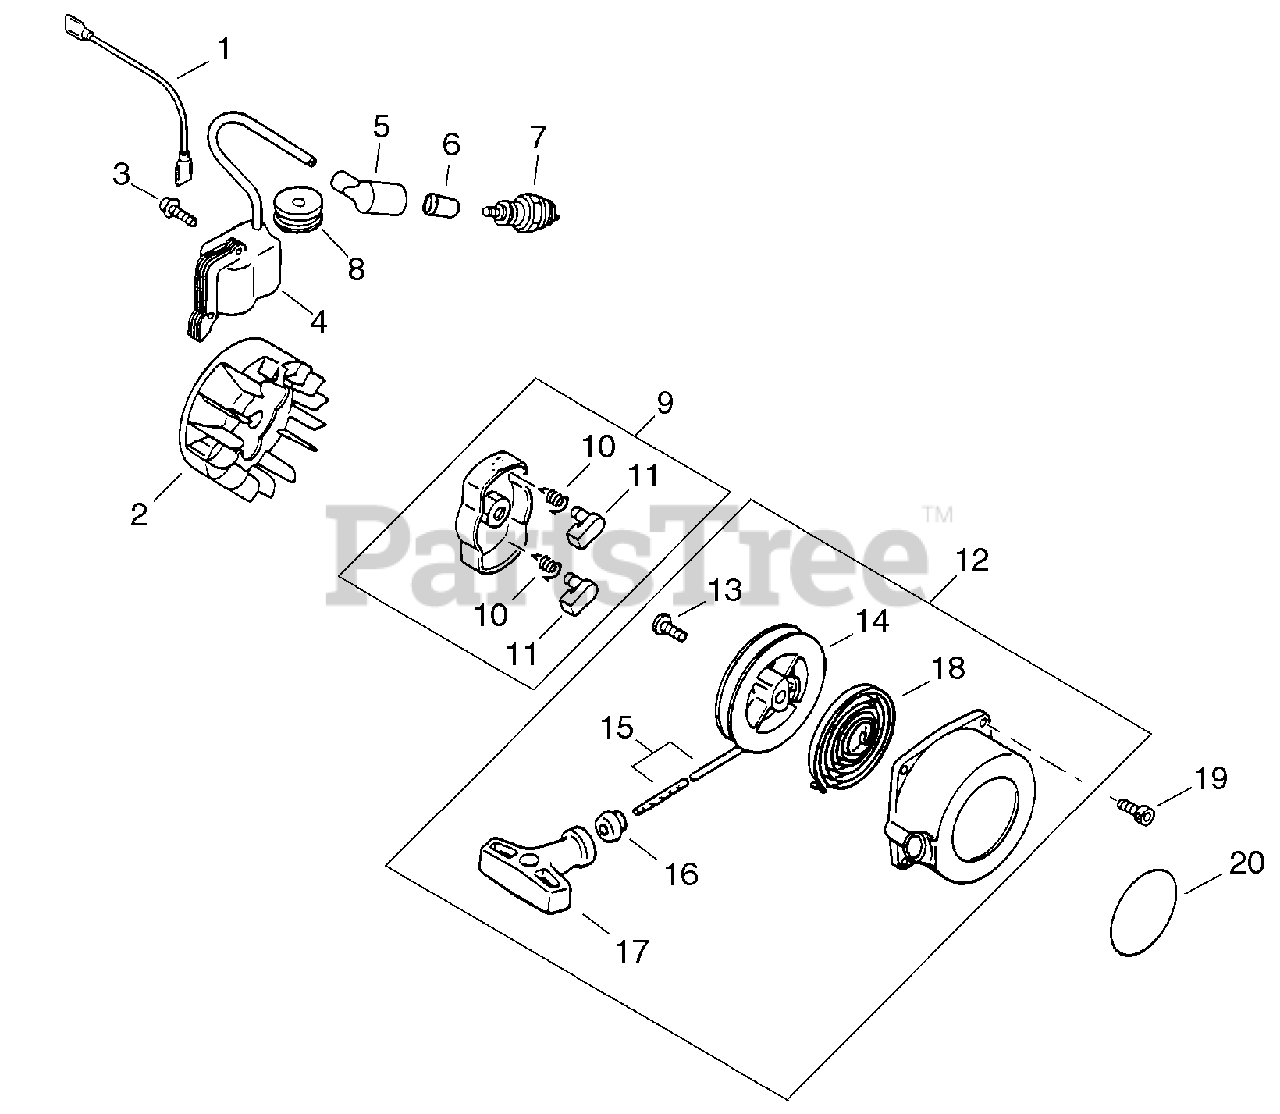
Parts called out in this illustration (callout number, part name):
1	LEAD
2	FLYWHEEL
3	SCREW 4×22
4	COIL, IGNITION
5	CAP, SPARK PLUG
6	ADAPTOR, SPARK PLUG - CAP
7	SPARK PLUG - BPMR7A
9	PAWL ASSY, STARTER
10	SPRING, RETURN
11	PAWL, STARTER - BLACK
12	STARTER ASSY, RECOIL
13	SCREW
14	REEL, ROPE
15	ROPE, STARTER 3.0×1000
16	GUIDE, ROPE
17	GRIP, STARTER
18	SPRING, RECOIL
19	BOLT 4×16
20	LABEL, RECOIL STARTER
